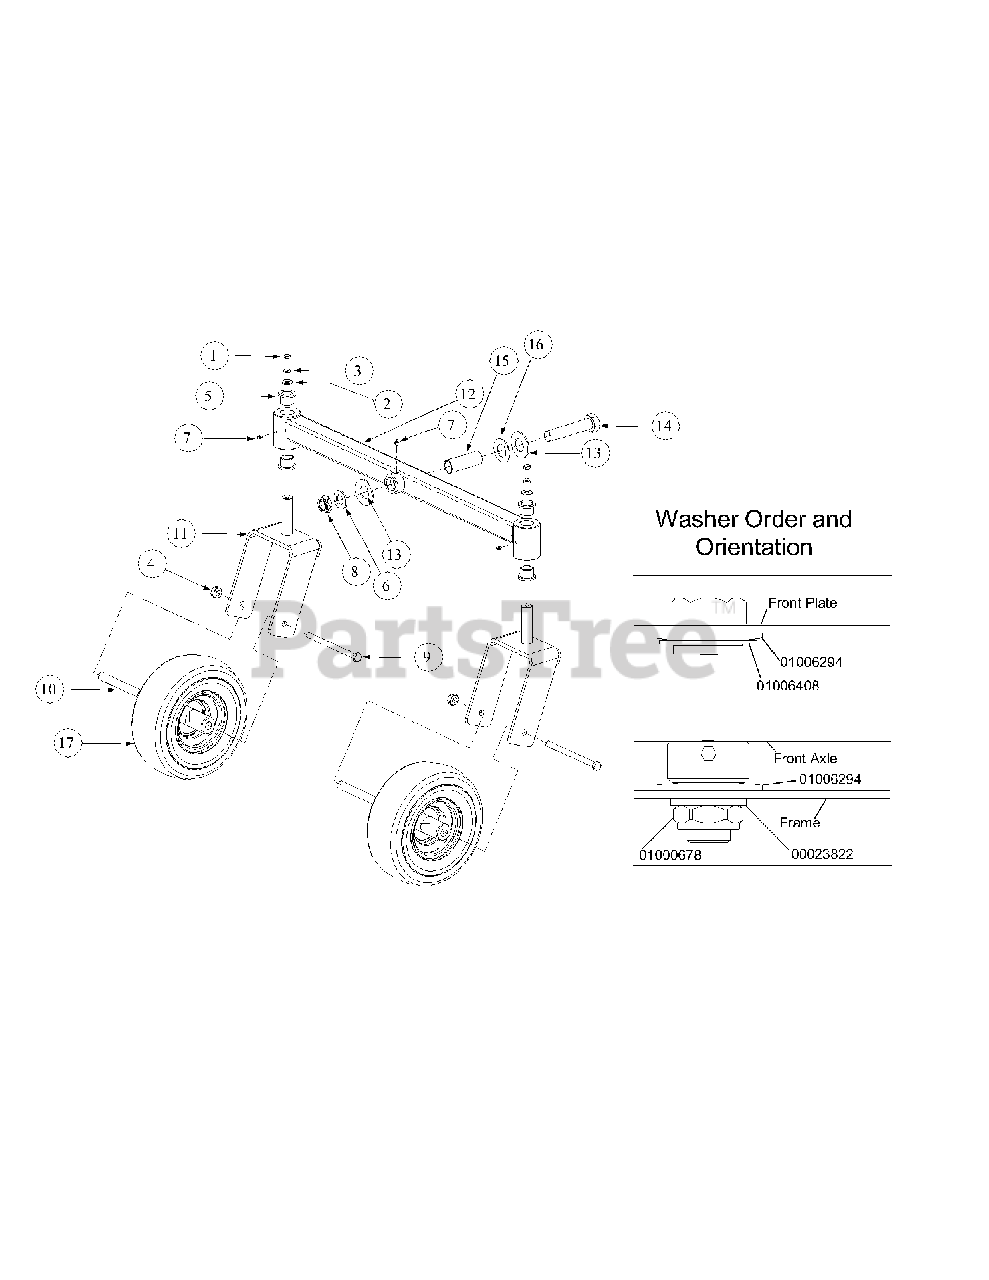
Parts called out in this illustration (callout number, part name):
1	Hex Cap Screw, 3/8-16, x 1
2	Flat Washer, .411 x 1.25 x 1.00
3	Lock Washer, 3/8
4	Center Lock Nut, 1/2-20
5	Flange Bearing, 1.013
6	Special Washer
7	Grease Fitting, 1/4-28 x 3/16
8	Jam Lock Nut, 1.0-14
9	Hex Cap Screw, 1/2-20 x 7.00
10	Spacer, .51 ID x .75 OD x 5.83 Lg
11	Caster Wheel Bracket Assembly
12	Narrow Front Axle Assembly
13	Belle Washer, 1.25 ID x 2.500 OD x .1
14	Hex Cap Screw, 1-14 x 5.0
15	Spacer, 1.005 ID x 1.25 OD x 3.6
16	Flat Washer, 1.25 ID x 2.25 OD x .075
17	Wheel Assembly, 11 x 4-5.00
